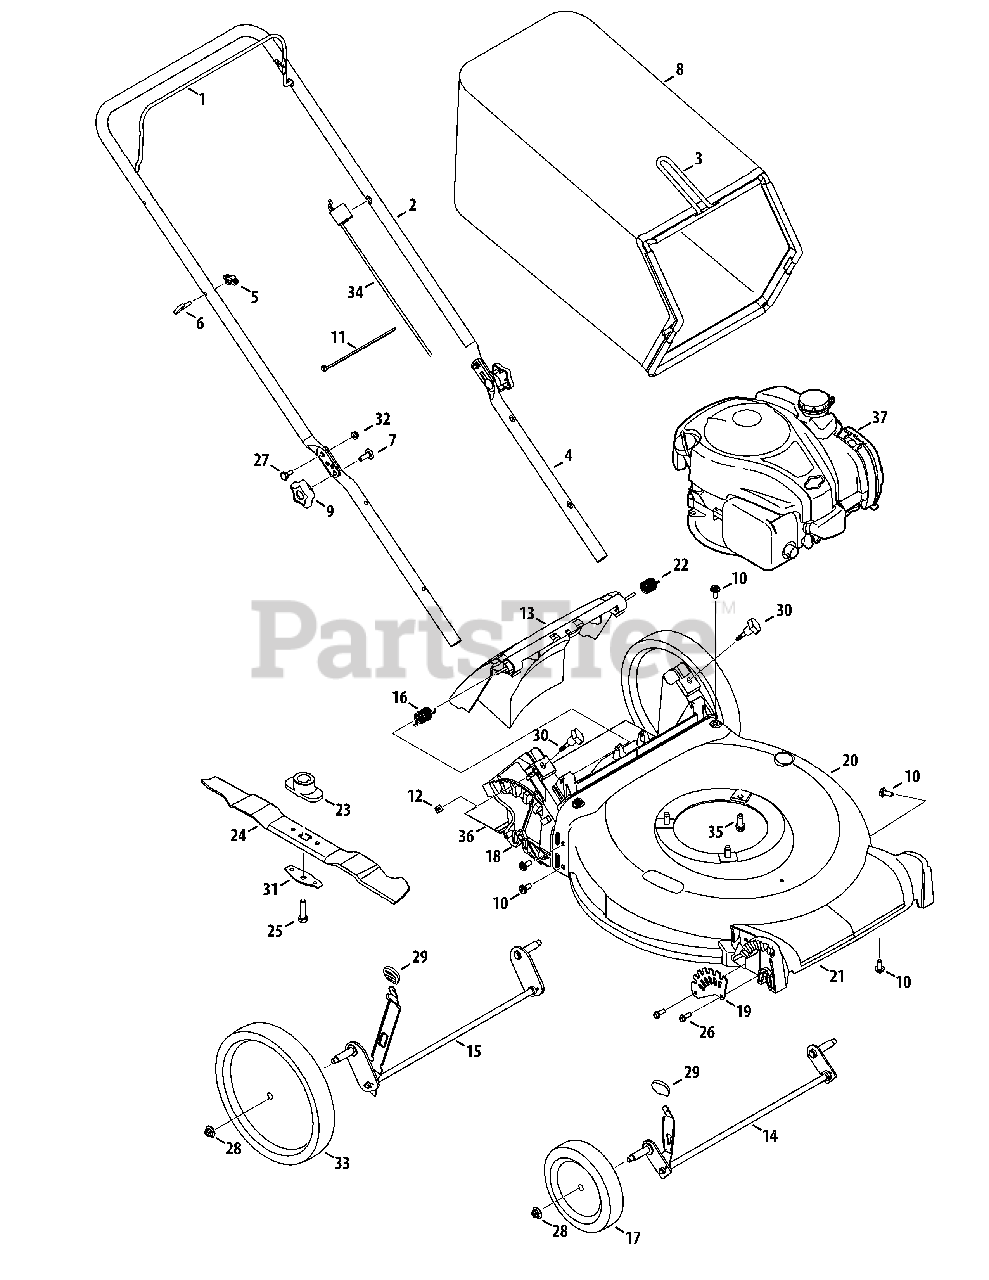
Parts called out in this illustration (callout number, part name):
1	Blade Control
2	Upper Handle
4	Lower Handle
5	Wing Nut
6	Rope Guide
7	Carriage Screw ,5/16-18
8	Grass Bag
9	Hand Knob
10	Screw, 5/16-14 x .750
11	Cable Tie
12	Nut, Sq., 1/4-20
13	Rear Discharge Door Assembly
14	Front Axle Assembly
15	Rear Axle Assembly
16	Torsion Spring - RH
17	Wheel, 7 x 1.8
18	Rear Baffle
19	Front Height Adjuster Plate
20	Deck - 21"
21	Front Cover
22	Torsion Spring - LH
23	Blade Adapter
24	Mulching Blade
25	Screw , 3/8-24 x 1.50
26	Screw, 1/4-15 x .750
27	Sldr. Screw, .375 x .126 x 1/4-20
28	Flange Lock Nut, 3/8-16
29	Adjustment Lever Knob
30	Wing Nut
31	Blade Bell Support
32	Nut, Flange Lock, 1/4-20
33	Wheel, 11 x 1.75
34	Control Cable
35	TT Sems Screw, 3/8-16 x 1.0
36	Trail shield
37	Replacement Engine 09P702-0007-F1
